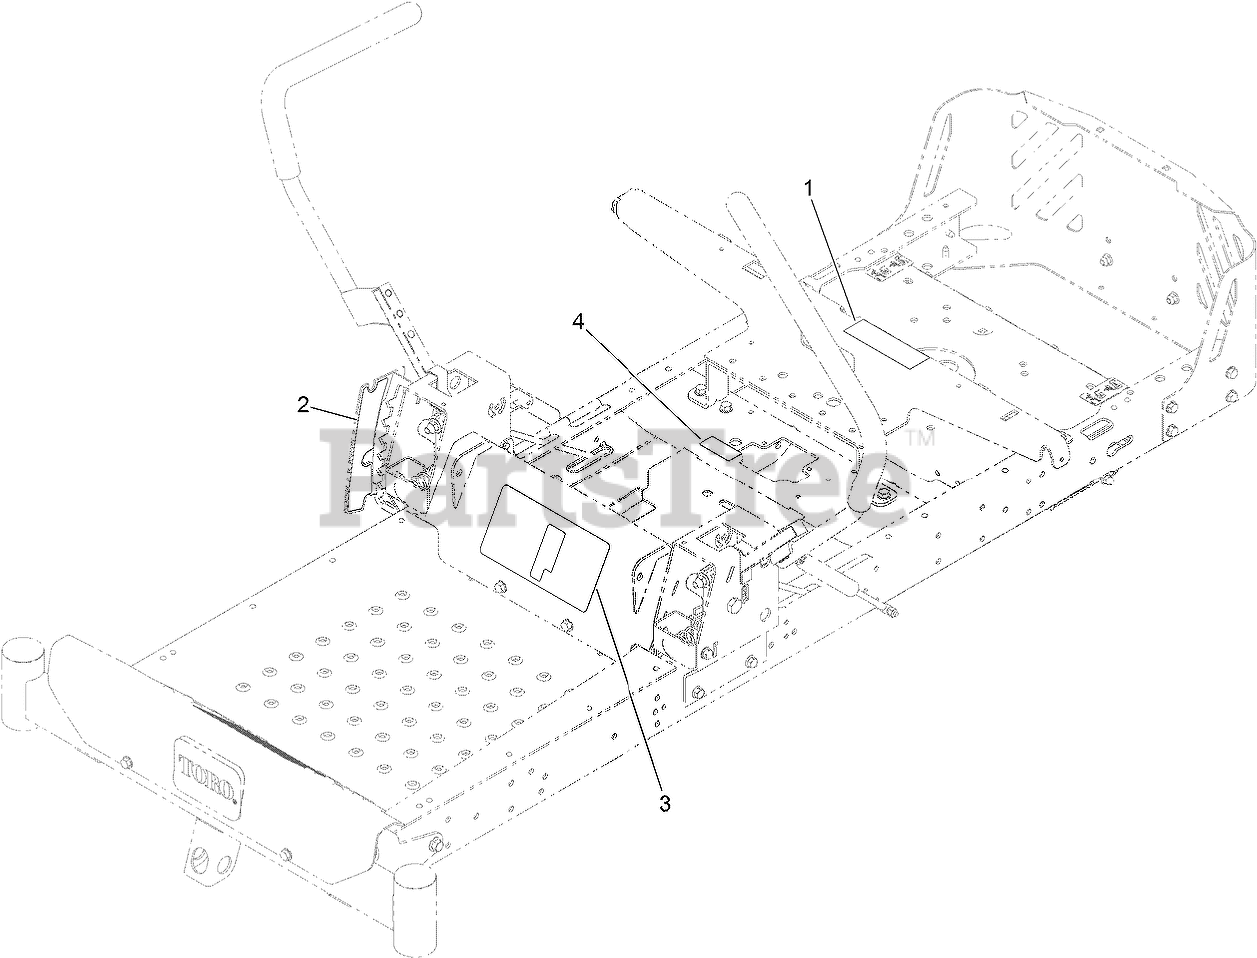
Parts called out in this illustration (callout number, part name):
1	DECAL-SERVICE, CE
2	DECAL-HOC
3	DECAL-CONTROL, SPEED
4	DECAL-LOCATION, SERVICE DEALER
